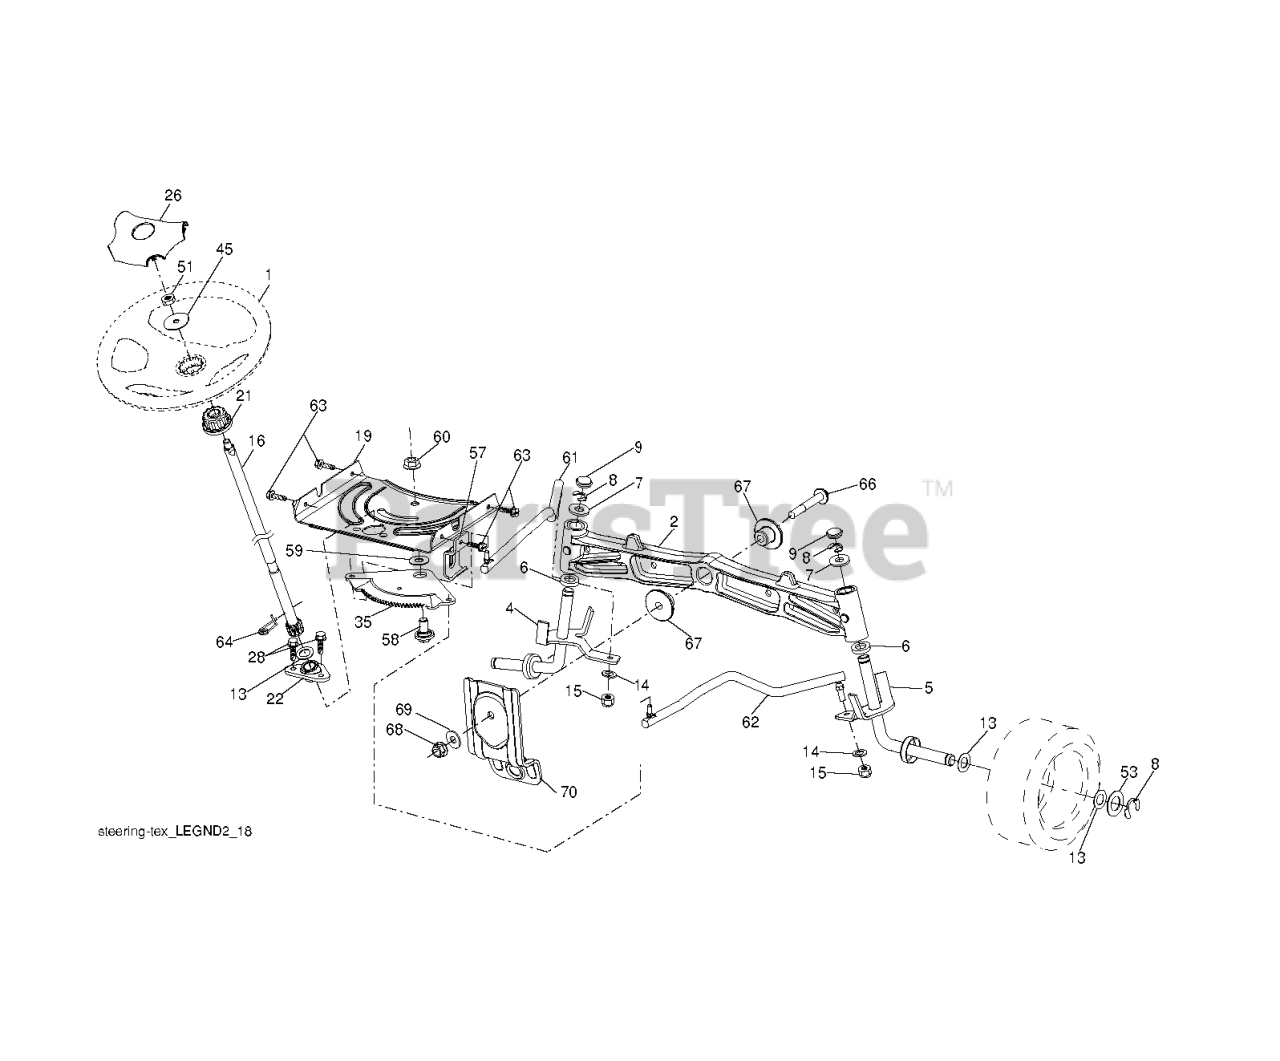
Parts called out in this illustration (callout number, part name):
1	STEERING WHEEL
2	AXLE.CAST.IRON
4	SPINDLE.WELDED.LH.16"TEX
5	SPINDLE.WELDED.RH.16"TEX
6	THRUST WASHER
9	CAP.SPINDLE.BLACK
14	WASHER, LOCK 3/8
15	NUT CROWNLOCK 3/8-24
16	SHAFT.STEER.STEALTH.DD
19	PLATE.STEER.DDL.NLT/NG
21	ADAPTER, WHEEL STNG..
22	BUSHING.ASM.STEERING.A
26	INSERT.CAP.STRG.WH.GRAY
28	SCREW, 3/8-16X3/4
35	GEAR.SECTOR.PLATE.DDL.
45	WASHER 9/16"ID, 2 3/8"OD
51	NUT.HEX.1/2-20
53	WASHER.HARDENED
57	BRKT.UPSTOP.GT/LT.TEX
58	BOLT.SHOULDER.SECTOR.P
59	WASHER.THURST.SECTOR.S
60	NUT FLANGE LOCK 5/8-11
61	DRAGLINK.LH.BALLSTUD.D
62	DRAGLINK.RH.BALLSTUD.D
63	SCREW
64	RETAINER.CLIP.SPRING.S
66	BOLT HEX FGHD 7/16-14 X 3 SERR
67	BUSHING.PM.FRONT AXLE
68	NUT.LOCK.FLANGE.7/16
69	WASHER.1.5X.505X.118
70	BRKT.DECK.SUSPENSION.F
